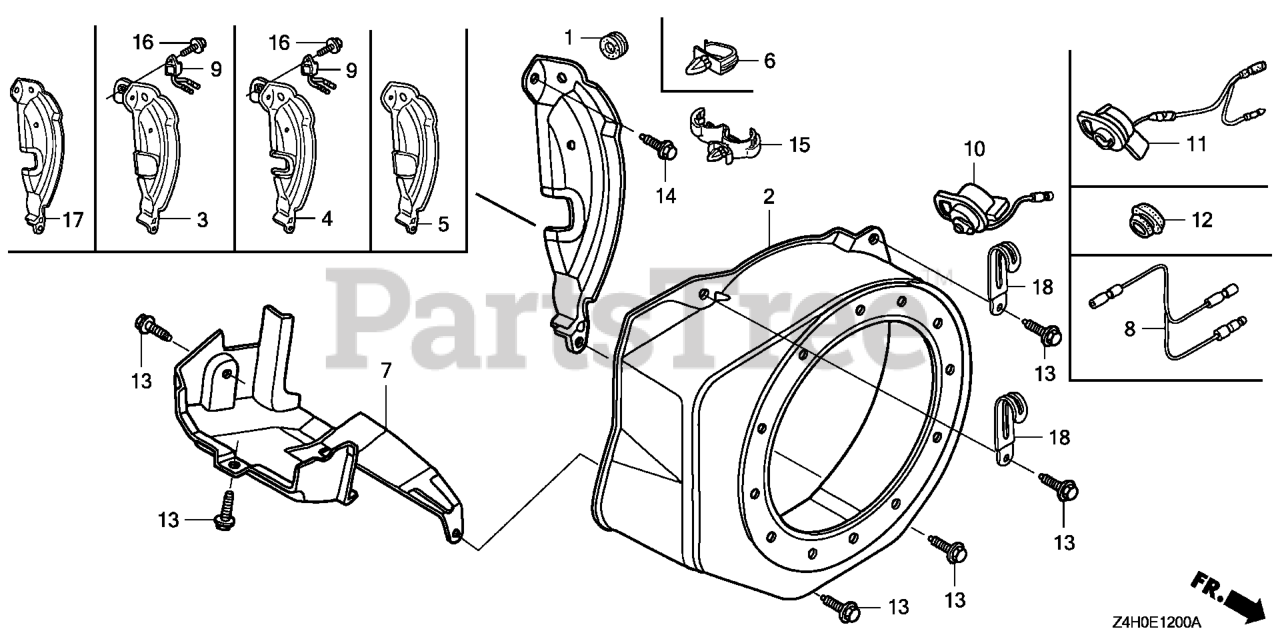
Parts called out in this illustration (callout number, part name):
1	GROMMET, ADJUSTING COVER
2	COVER, FAN *NH1* (BLACK)
3	PLATE, SIDE (OIL ALERT)
9	ALERT UNIT, OIL (CHONGQING LIHUA)
9	ALERT UNIT, OIL
11	SWITCH ASSY., ENGINE STOP (TOYO DENSO)
11	SWITCH ASSY., ENGINE STOP (MINDA)
13	BOLT, FLANGE (6X12) (CT200)
14	BOLT, FLANGE (6X20) (CT200)
15	CLIP, HARNESS
16	BOLT, FLANGE (6X8)
